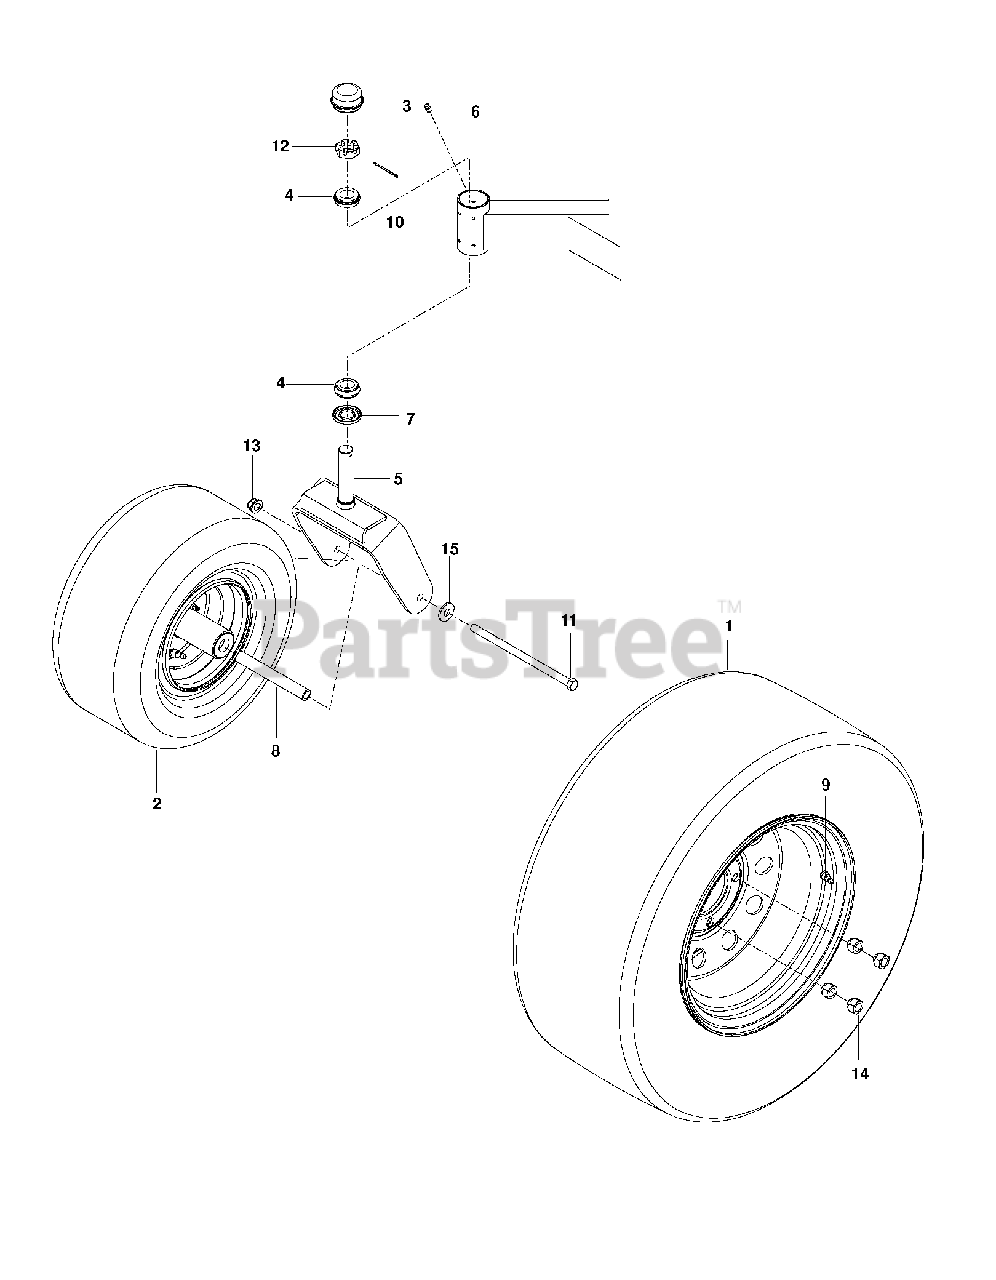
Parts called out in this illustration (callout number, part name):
1	Wheel Assembly, 22 X 10-10.Silve.Ztr
2	Caster Tire Assembly, 13 X 6.5-6 Silver
3	GREASE CAP
4	TAPERED ROLLER BRG
8	SPACER, PIVOT
9	VALVE STEM TR-412
10	COTTER PIN 1/8 X 2
11	HEX SCREW 1/2-13 X 9.5 GR5
12	NUT 1"C HEX SLOTTED
13	NUT, 1/2-13 HEX FLG NYLOC ZD
14	LUG NUT 1/2F
15	WASH USS FLAT 1/2
